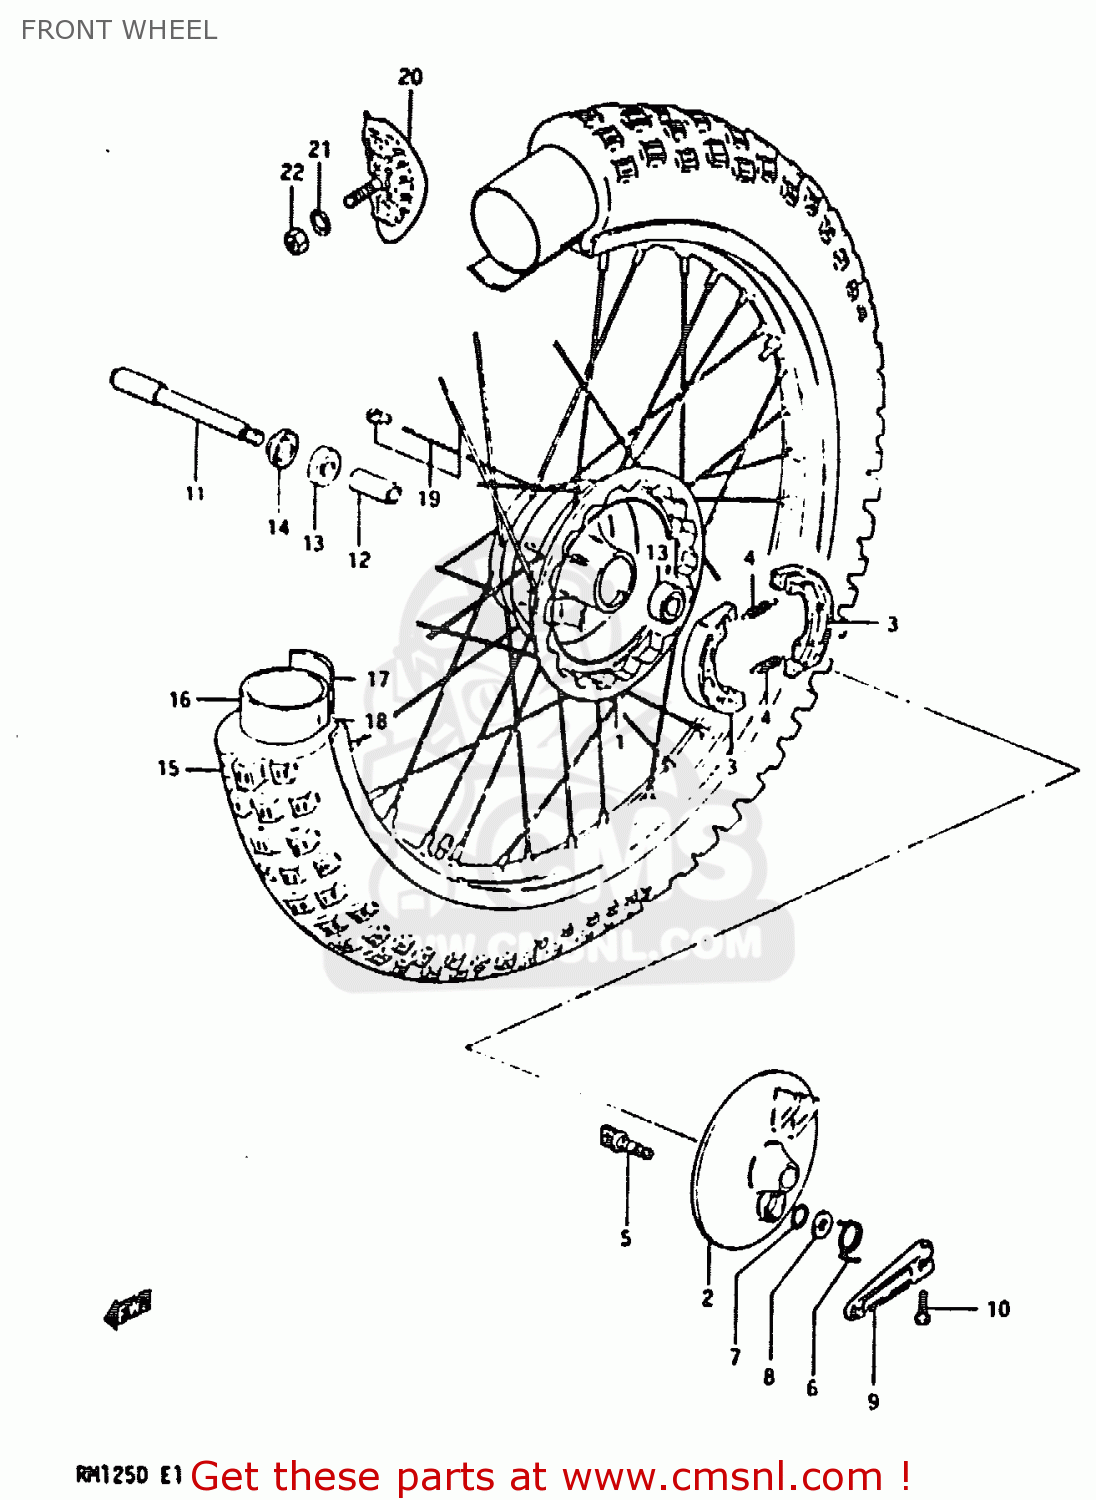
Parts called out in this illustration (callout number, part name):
1	HUB,FRONT
2	PANEL,FRONT HUB
3	SHOE,BRAKE
4	SPRING
5	CAM,FR BRAKE
6	SPRING
7	O RING(D:2.5,ID:11.4)
8	WASHER(12.5X20X1)
9	LEVER,FRONT BRAKE CAM
10	BOLT
11	AXLE,FRONT
12	SPACER,FRONT HUB BEARING
13	BALL BEARING 15X35X11
14	SPACER,FRONT AXLE,RIGHT
15	TIRE,FRONT
16	TUBE
17	PROTECTOR,WHEEL,INNER
18	RIM,FRONT WHEEL
19	SPOKE SET,FRONT
20	STOPPER,BEAD
21	WASHER
22	NUT 8MM
